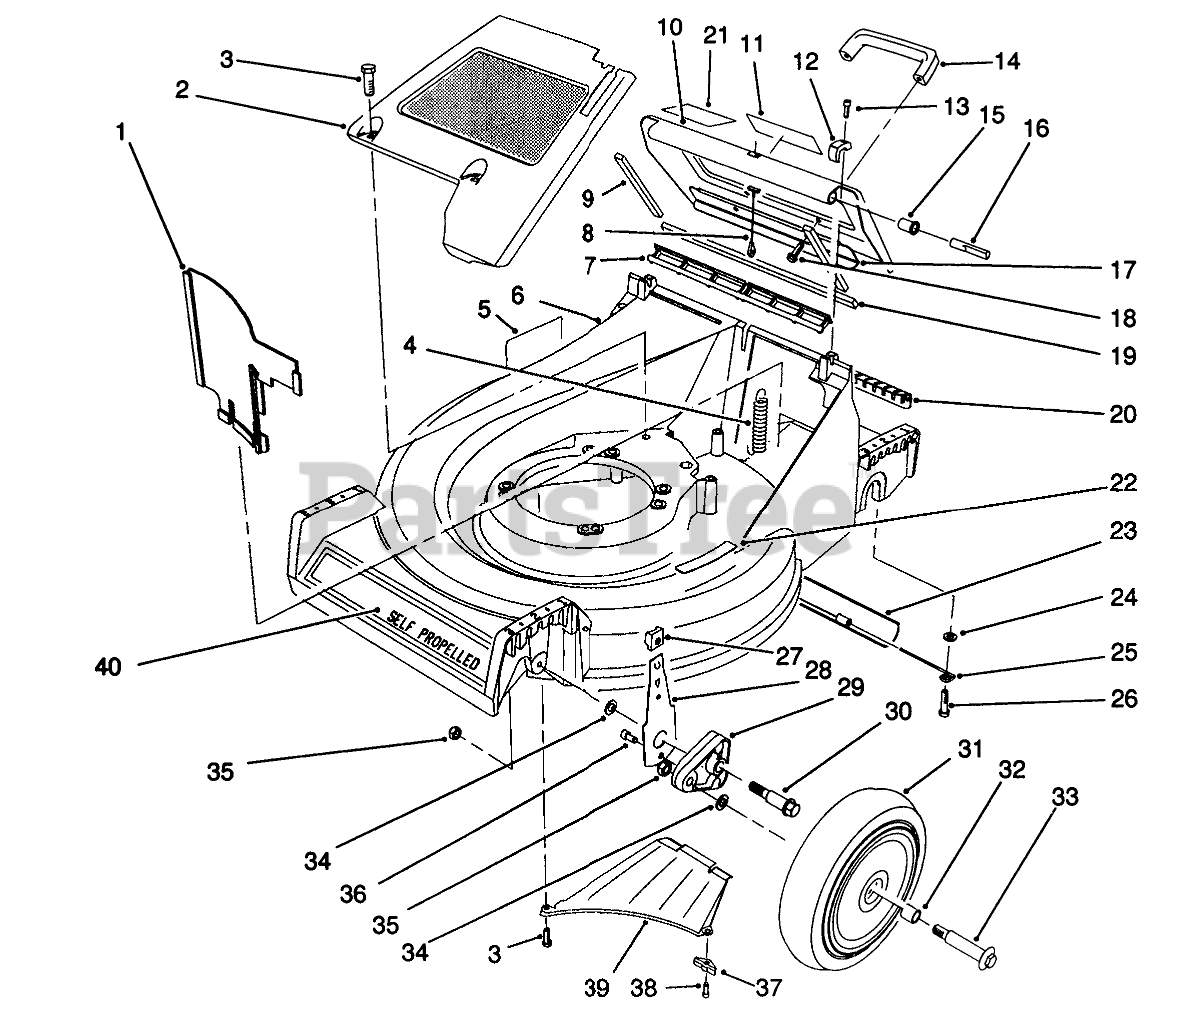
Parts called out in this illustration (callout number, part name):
1	PANEL-VERTICAL
2	PaneI-Screen
3	SCREW-HWHTF
4	EXTENSION-SPRING
5	Decal Danger
6	21" Housing Assembly (Incl. Ref. #5, 22)
7	DOOR SEAL
8	DOOR CABLE
9	DOOR SIDE SEAL
10	Door-Discharge (Incl. Ref. #9, 11, 17 & 19)
11	DECAL - DANGER
12	HINGE CLAMP
13	SCREW-HSH
14	HANDLE-DOOR
15	DOOR BUSHING
16	HINGE PIN
17	DOOR - BRACE
18	SCREW-HWH
19	DOOR END SEAL
20	ACCESS COVER
21	DECAL FRENCH REGUL.
22	DECAL - STEP PAD INT'L
23	TRAILING SHIELD
24	WASHER-PLAIN
25	SHIELD HANGER
26	SCREW-SHOULDER
27	KNOB-ARM
28	FRONT SPRING ARM ASM
29	ARM-PIVOT, FRONT
30	BOLT-SHOULDER
31	Wheel & Tire Assembly (Incl. Ref. #30)
32	BUSHING
33	WHEEL BOLT
34	WASHER
35	NUT-LOCK
36	SCREW-HSH, THREAD FORMING
37	Bracket-Discharge
38	SCREW-HWHTF
39	Ramp Discharge
40	DECAL - 53 CM
